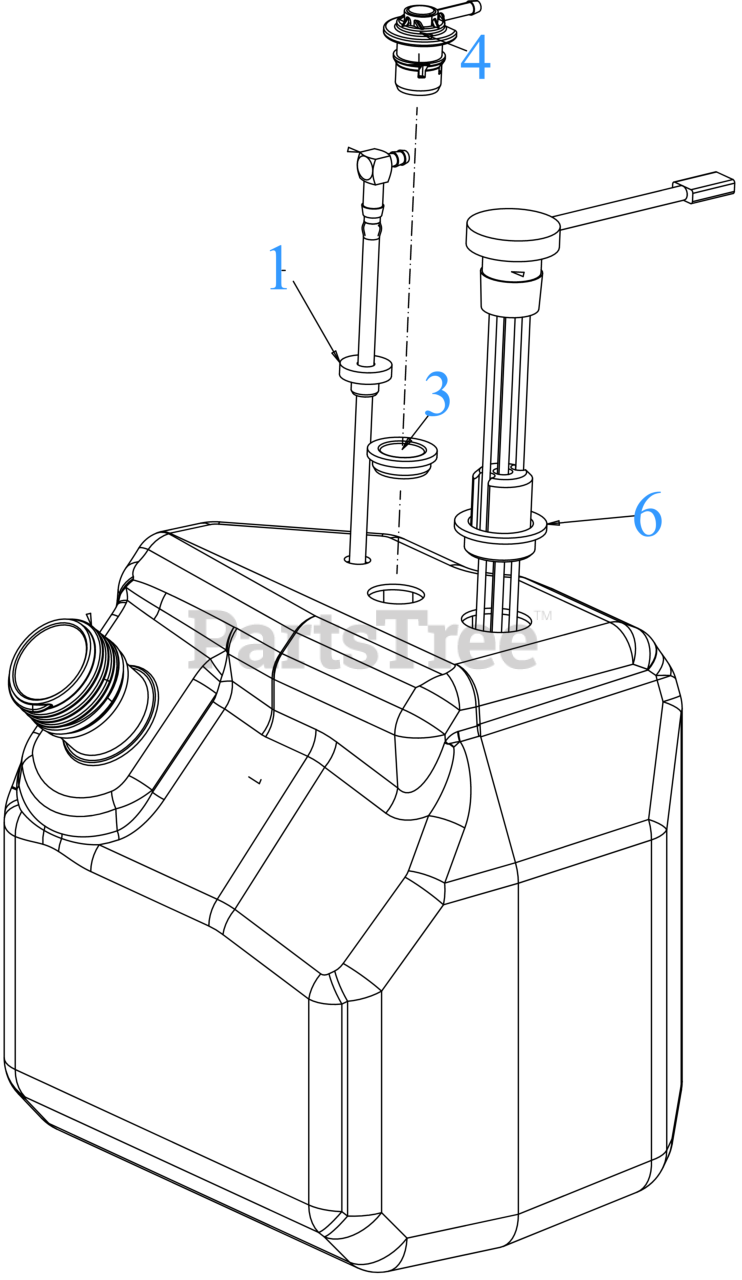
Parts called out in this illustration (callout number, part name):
1	GROMMET-FUEL TANK
3	RUBBER GROMMET 23.0 ID x 35.5 OD
4	ROLLOVER FUEL VALVE
6	FUEL GAUGE GROMMET
